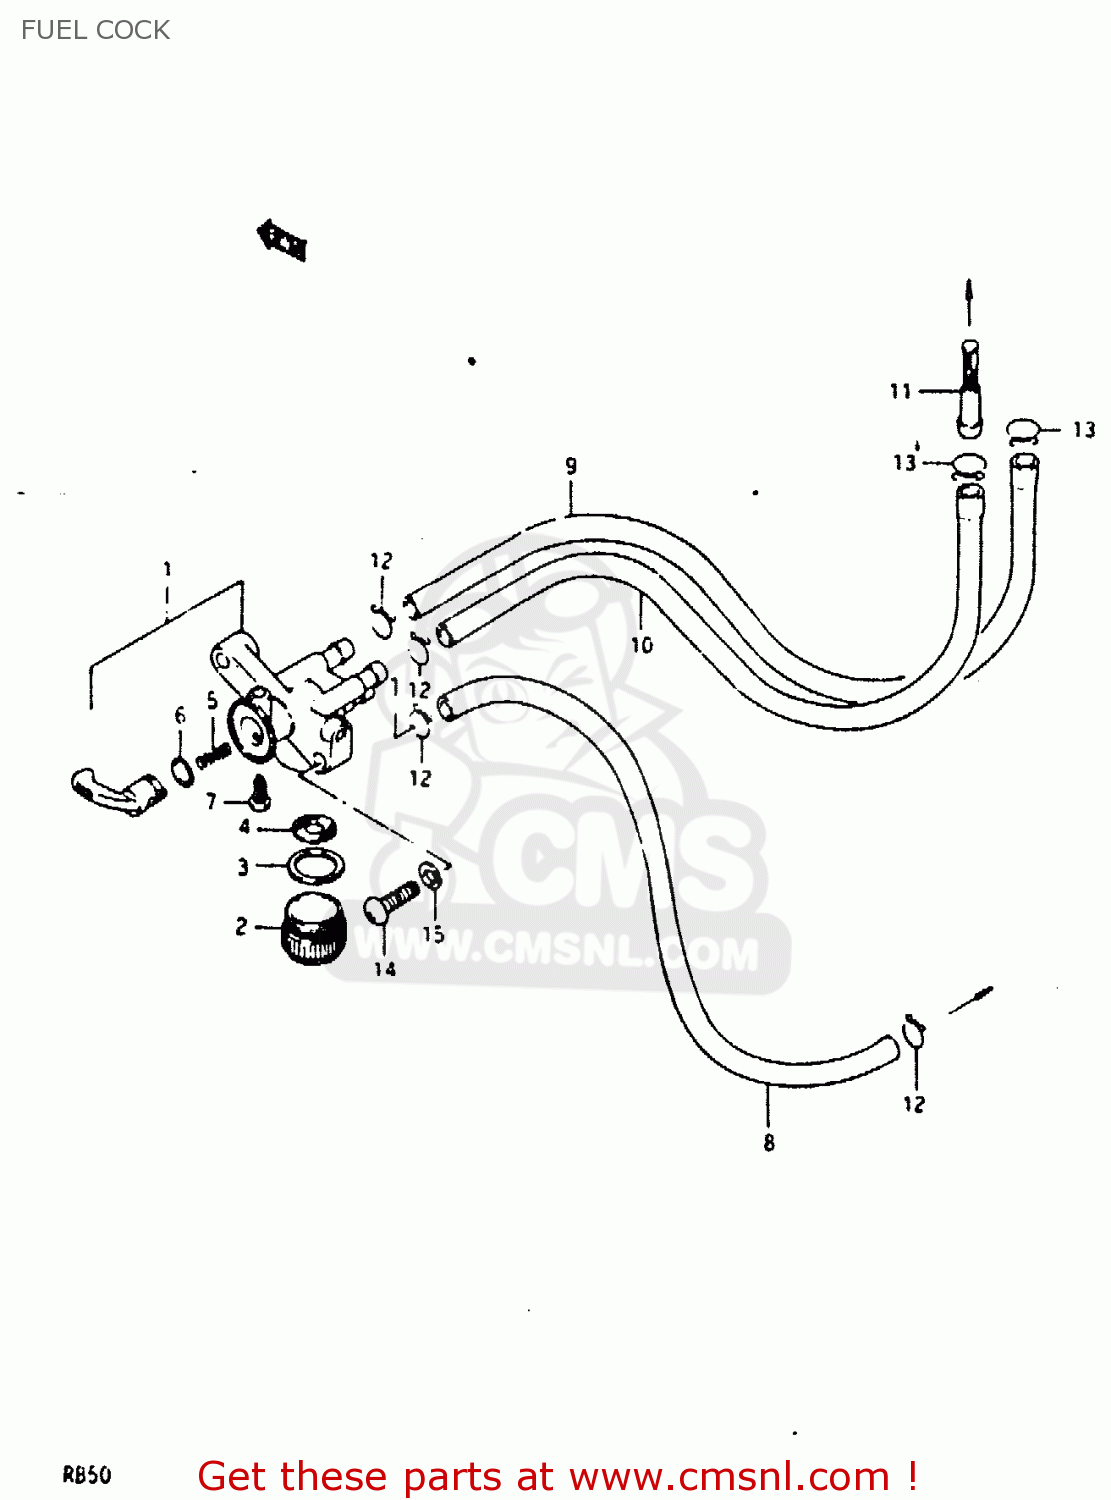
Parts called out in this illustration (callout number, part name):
1	COCK ASSY,FUEL
2	CUP
3	GASKET,FUEL FILTER CUP (NAS)
4	NET,FILTER
5	SPRING
6	O RING,LEVER
7	SCREW
8	HOSE,FUEL
9	HOSE,FUEL
10	HOSE,FUEL
11	FILTER,FUEL
12	CLIP
13	CLIP
14	SCREW 5X20
15	LOCK WASHER
